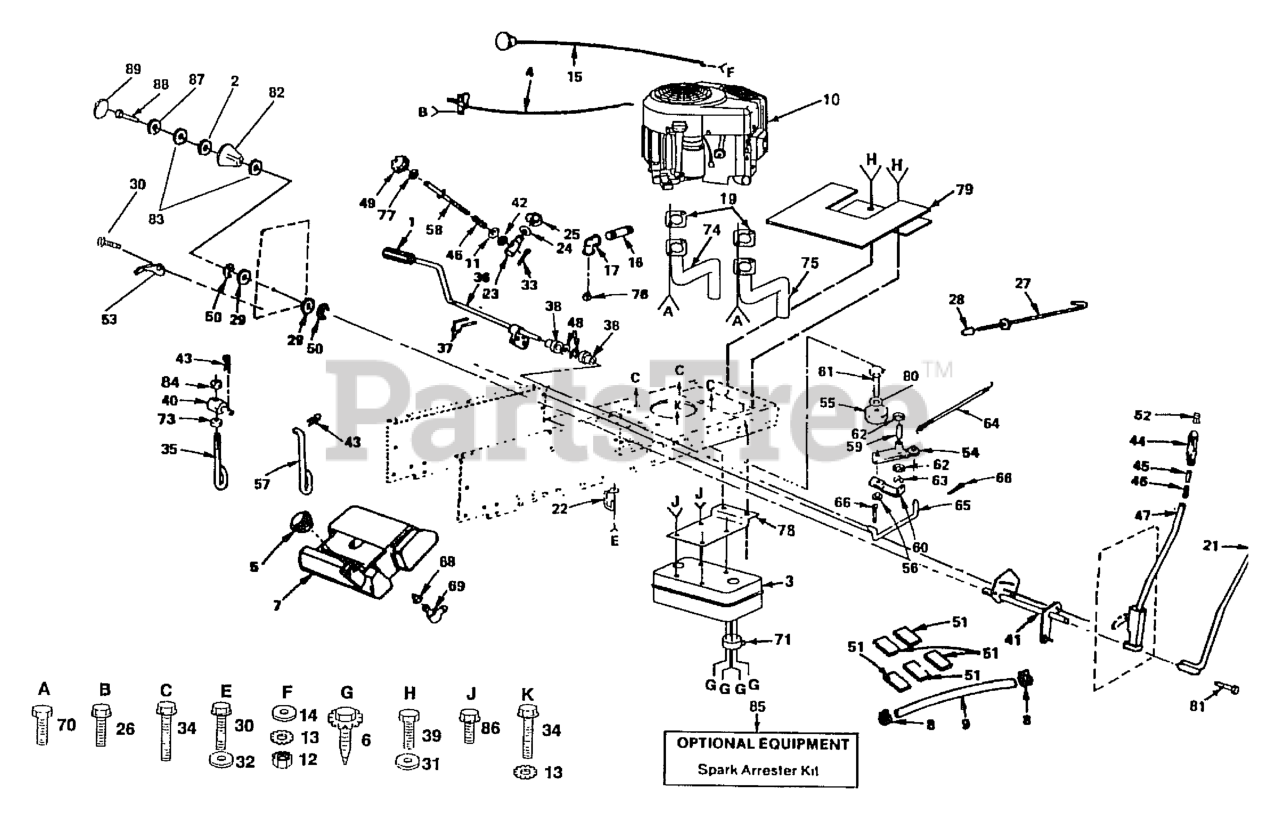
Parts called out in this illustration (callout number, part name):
1	COVER, PEDAL (1 2)
4	CONTROL.THROT.RH.BLK.FLG.44.75
5	FUEL CAP ASS'Y
6	Screw, Spider Lock
7	FUEL TANK LT
8	HOSE CLAMP
9	FUEL LINE 54"
10	Engine, Briggs & Stratton, Model Number 303777
12	NUT
13	LOCKWASHER
14	WASHER
15	CHOKE CONTROL
16	Nipple, STD Pipe
17	ELBOW
19	Gasket, Muffler
21	LEVER ROD LT
22	BELT RETAINER
23	TRUNION LT
24	Washer 15/32 x 3/4 x 16 Gauge
25	Ring, Klip
26	SCREW LT
27	ROD BRAKE PARK
28	PLUNGER CAP
29	Washer 29/32 x 1-1/4 x 16 Gauge
30	SCREW
31	WASHER
32	WASHER
33	COTTER PIN
34	SCREW LT
35	LINK ADJ T
36	SHAFT FOOT PEDAL
37	PIN.ROLL.3/16 X 1"
38	BEARING.NYLON
39	SCREW.THDROL.5/16-18X3/4.TTY
40	TRUNNION T
41	Shaft Assembly, Lift
42	NUT T
43	RETAINER-SPRNG RB
44	GRIP HANDLE
45	PLUNGER BUT KIT
46	SPRING**
47	LIFT LEVER KIT
48	WASHER LT
49	HDLE ADJ LIFT
51	PAD-SPACER T
52	PLUNGER BUT KIT
53	POINTER HGT INDAT
55	IDLER PULLEY
57	LIFT LINK LT
58	ROD LIFT LT
59	BEARING LT (2 2)
60	RETAIN BELT
61	BOLT
64	SPRING, RETURN LT
65	LINK, CLUTCH LT
66	COTTER PIN
68	BUSHING OUTLET T
69	FUEL TANK STEM GT
70	Bolt, Metric
71	DEFL MUFFLER LTV
73	NUT **
74	TUBE ASSY EXH LH
75	TUBE ASSY EXH RH
76	Plug, Drain, Oil
77	NUT
78	BRACKET MUFFLER
79	HEAT SHIELD
80	WASHER
81	BOLT
82	HEIGHT INDICATOR
84	NUT LOCK YTH
85	SPARK ARREST
86	SCREW
87	WASHER.LOCK.HVY.HLCL.SPR.5/16
88	BOLT.FIN.HEX.5/16-18UNC X 1.00
